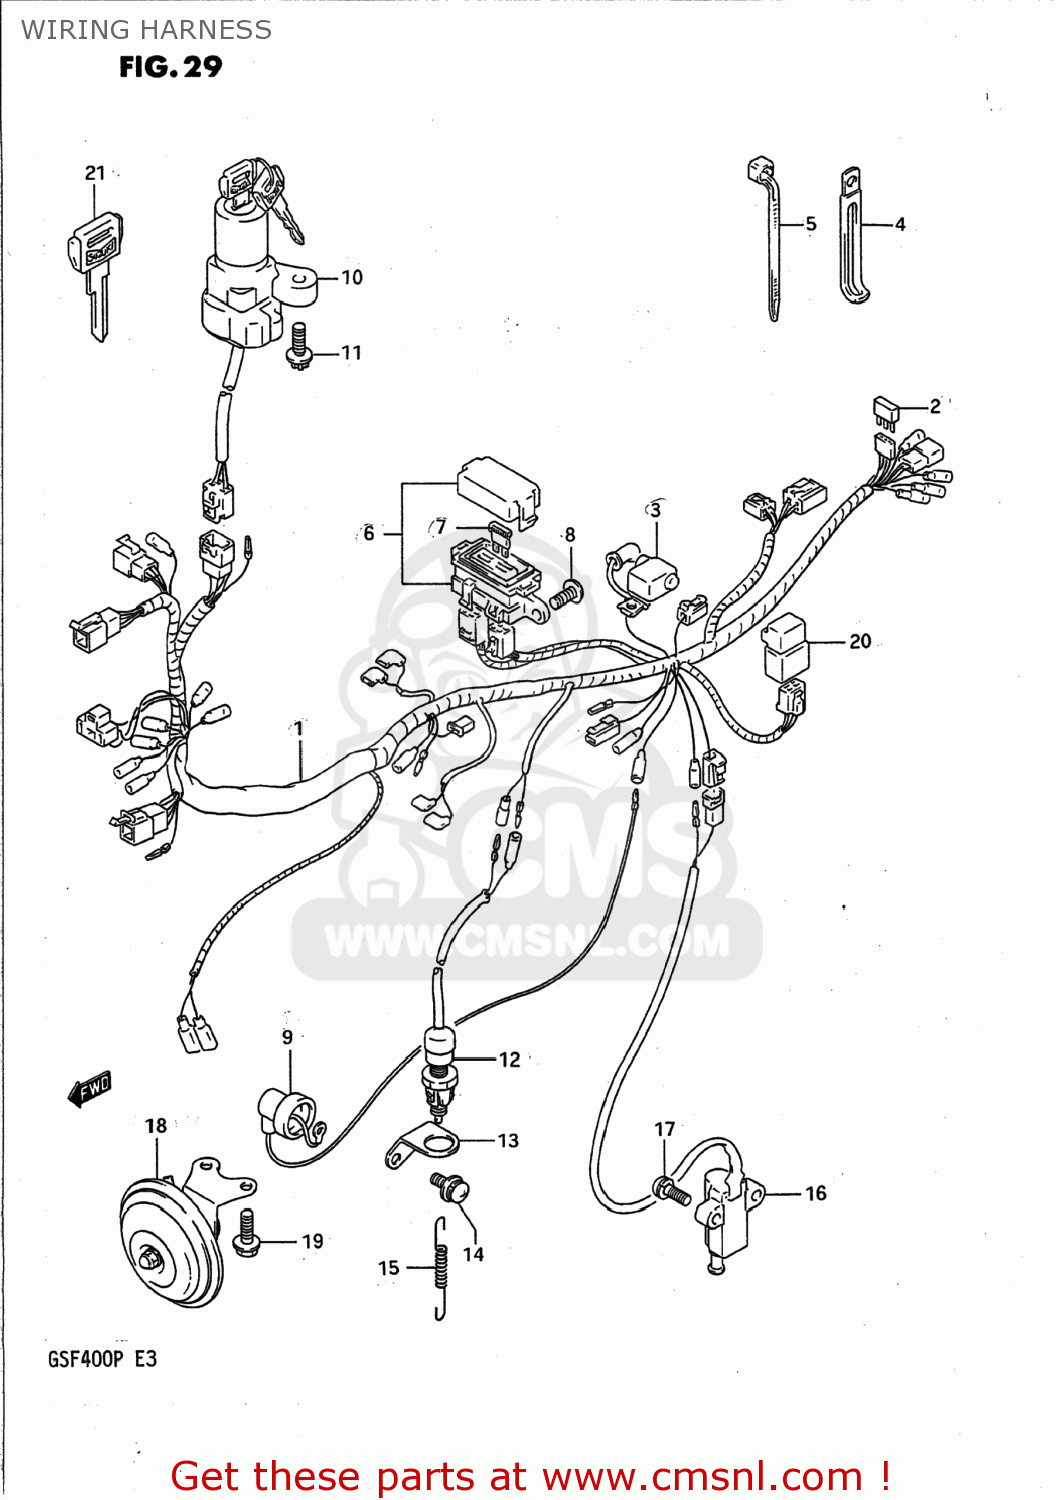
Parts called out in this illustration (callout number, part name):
1	HARNESS,WIRING
2	DIODE(STANLEY DE8804)
3	CAP,BATTERY PLUS
4	CLAMP
5	CLAMP
6	BOX ASSEMBLY,FUSE
7	FUSE(10A)
8	SCREW
9	WIRE
10	LOCK ASSEMBLY,STEERING
11	SCREW(6X18)
12	SWITCH ASSEMBLY,STOP LAMP
13	BRACKET,STOP LAMP SWITCH
14	SCREW
15	SPRING
16	SWITCH ASSEMBLY,SIDE STAND
17	BOLT 6X20
18	HORN ASSEMBLY
19	BOLT
20	RELAY ASSEMBLY
21	KEY,BLANK
